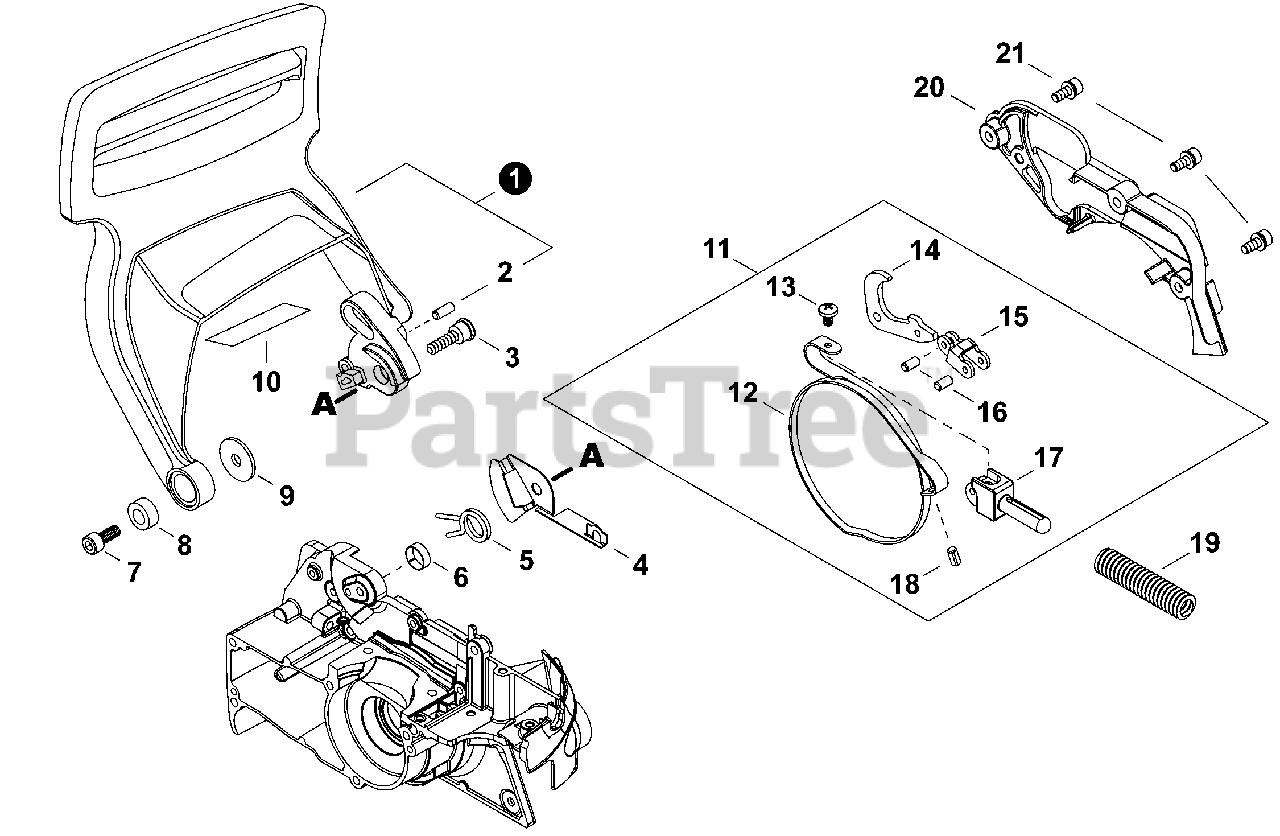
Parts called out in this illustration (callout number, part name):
1	LEVER ASSY, BRAKE
2	PIN, LOCATING 4×8
3	BOLT, ADHESIVE M4×38
4	PLATE, RETAINING
5	SPRING, TORSION
6	COLLAR 8
7	BOLT, ADHESIVE 5
9	WASHER 5
10	SHIELD, HEAT 35×60×0.10
11	BRAKE ASSY, BAND
12	BAND, BRAKE
13	SCREW, TAPPING M4×10
14	LEVER, BRAKE
15	STRAP, TIE
16	PIN 3×12
17	CONNECTOR, BRAKE
18	PIN, SPRING 4×10 MM
19	SPRING, BRAKE
20	COVER, BRAKE
21	BOLT, ADHESIVE M4×10
